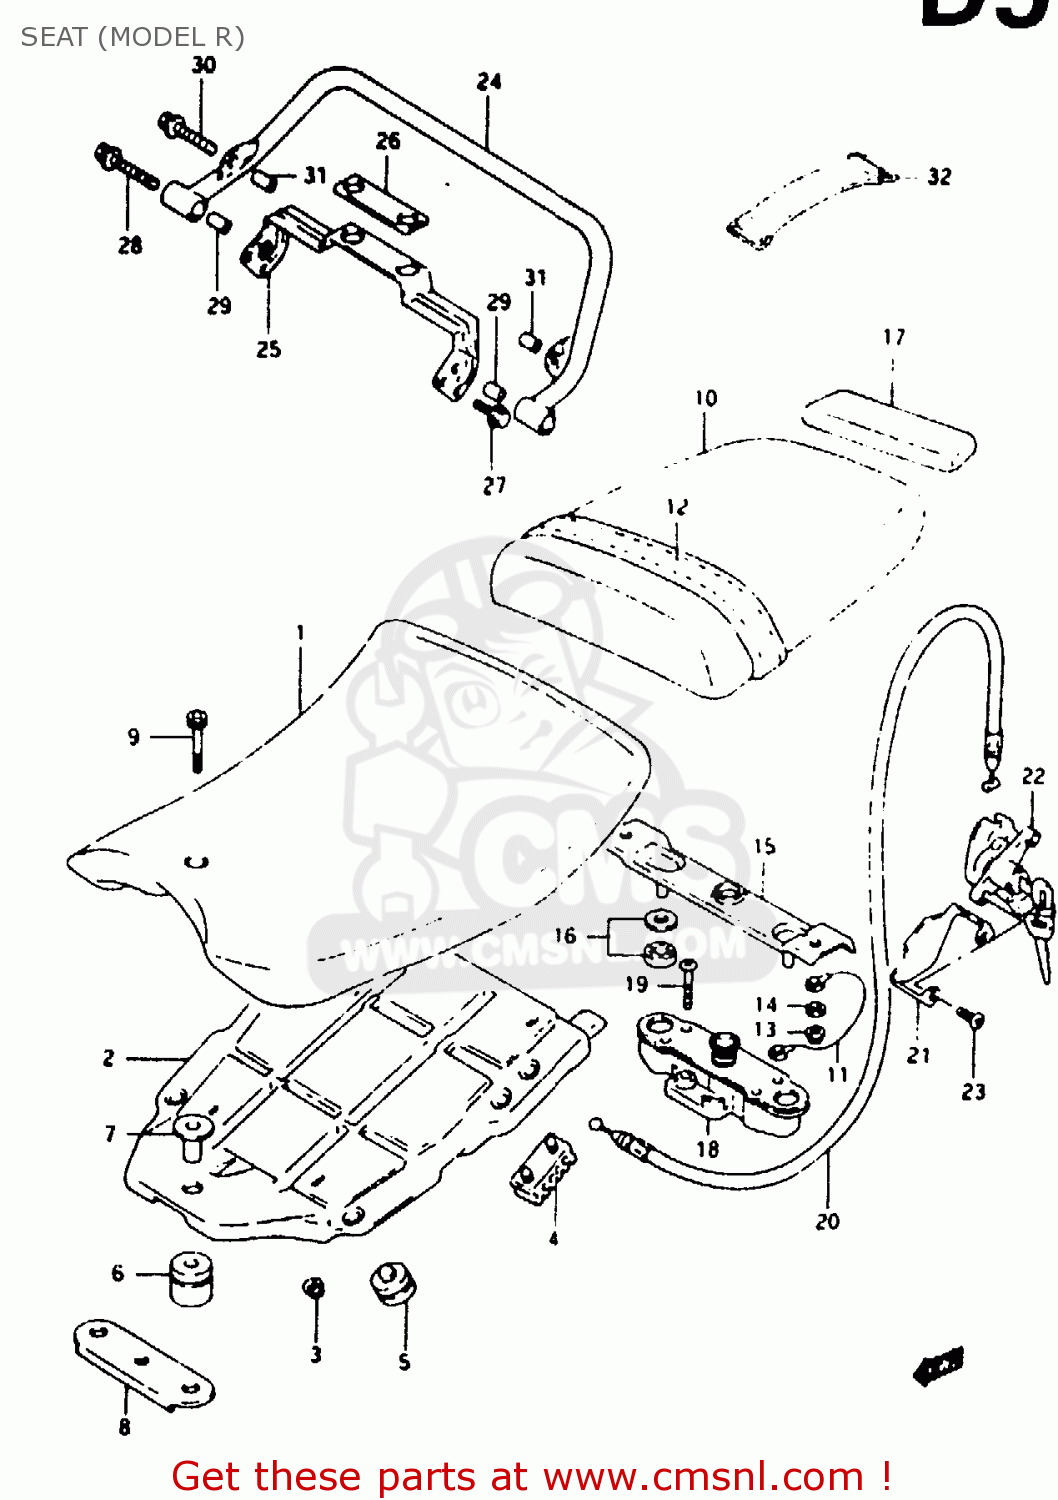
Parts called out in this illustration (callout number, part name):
1	SEAT ASSY (BLACK)
2	FRAME, SEAT BOTTOM
3	NUT, LICENSE
4	CUSHION,SIDE
5	CUSHION
6	CUSHION,SEAT
7	COLLAR,FR
8	PLATE,SEAT FR
9	BOLT
10	SEAT ASSY, PILLION (BLUE)
11	CABLE, PILLION SEAT
12	BAND, SEAT (BLUE)
13	NUT
14	WASHER
15	STRIKER,SEAT LOCK
16	CUSHION
17	EXTENTION
18	LOCK ASSY,SEAT STRIKER
19	SCREW 6X30
20	CABLE,SEAT LOCK CABLE
21	PLATE,SEAT LOCK GUARD
22	LOCK SET,SEAT & HELMET
23	SCREW
24	GRIP,RR
25	BRACE, REAR GRIP
26	CUSHION, CENTER COVER
27	BOLT
28	BOLT (8X80)
29	SPACER, FRONT
30	BOLT
31	SPACER, REAR
32	BAND
